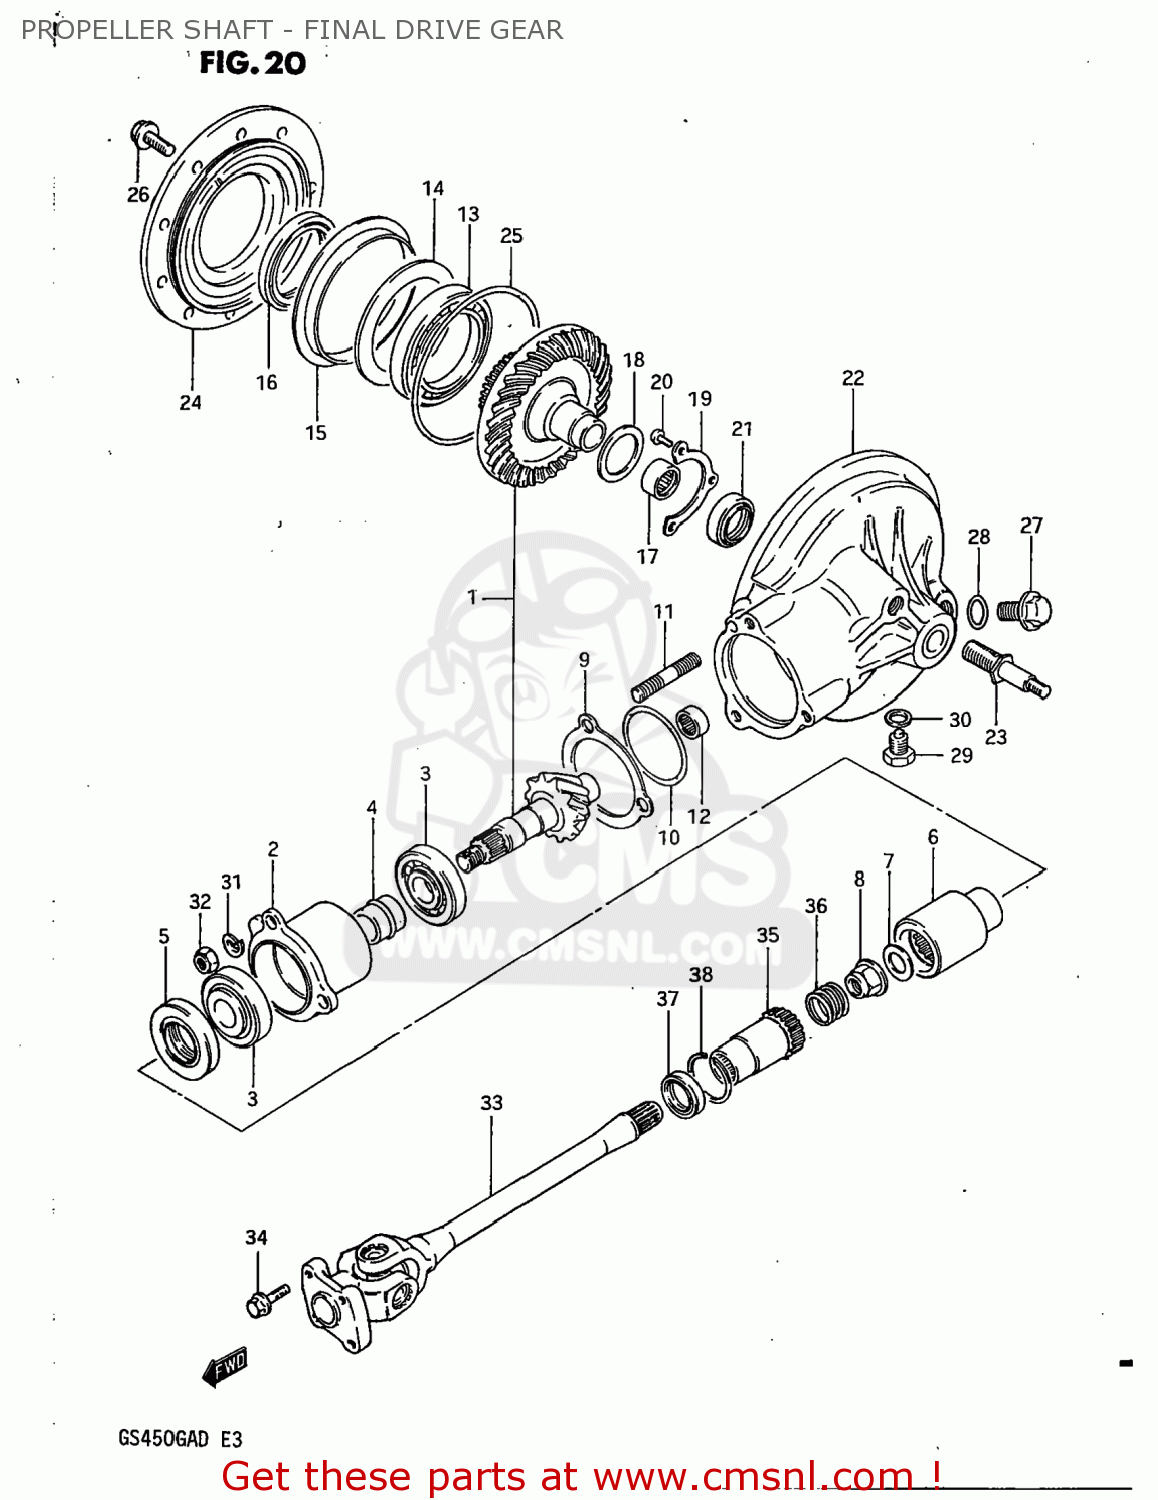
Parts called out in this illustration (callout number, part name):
1	GEAR SET,FINAL BEVEL (N
2	HOUSING,DRIVE GEAR
3	BEARING
4	SPACER
5	SEAL,OIL(32X54X7)
6	GEAR,FINAL DRIVE
7	WASHER(14X29X4)
8	NUT
9	SHIM,DRIVE GEAR HOUSING
10	O RING(D:2.4,ID:62.6)
11	STUD
12	BEARING
13	BEARING(70X110X13)
14	SHIM,DRIVEN GEAR BEARING T0.35
15	PLATE,FINAL DRIVEN BRG OIL
16	SEAL,OIL(70X96X16)
17	BEARING(32X46X17.7)
18	SHIM,FINAL DRIVEN GEAR
19	RETAINER,FINAL DRIVEN GEAR BRG
20	SCREW 6X12
21	SEAL,OIL(30X42X7)
22	CASE,FINAL GEAR
23	STUD
24	CASE,FINAL GEAR BEARING
25	O RING(D:3.5,ID:131.6)
26	BOLT
27	PLUG
28	O RING(D:2.4,ID:17.8)
29	PLUG
30	GASKET(14X19.2X2) (NAS)
31	LOCK WASHER
32	NUT
33	SHAFT ASSEMBLY,PROPELLER
34	BOLT(8X17)
35	COUPLING,PROPELLER SHAFT
36	SPRING
37	SEAL,OIL(30X40.5X5.5)
38	CIRCLIP
